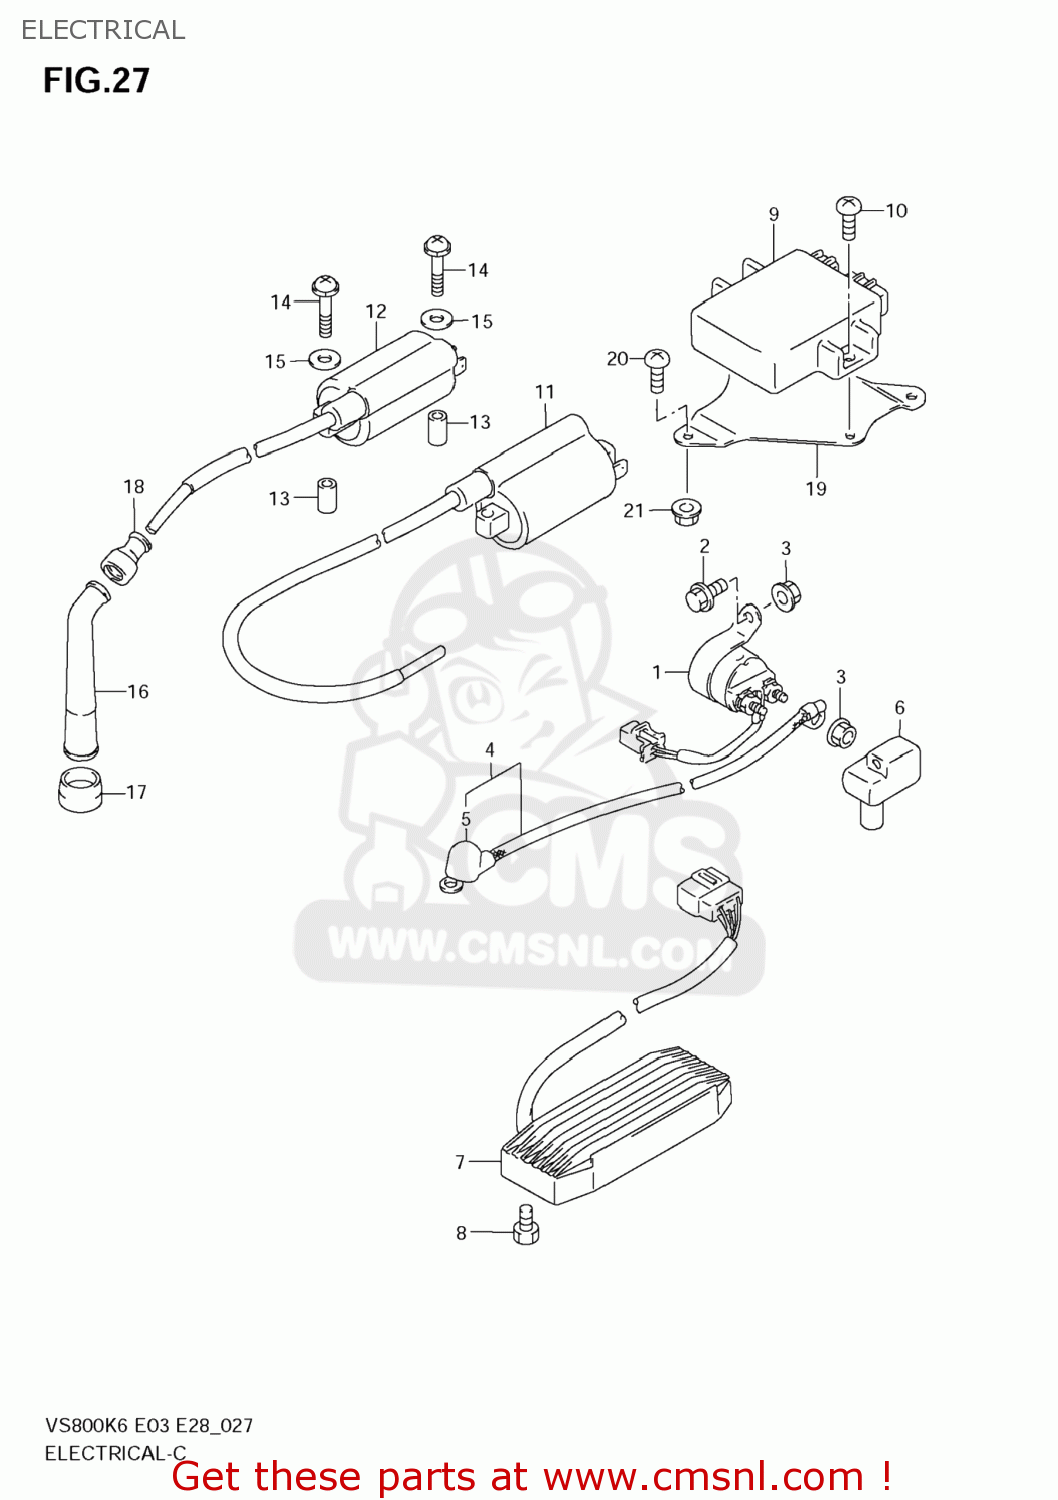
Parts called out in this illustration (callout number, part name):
1	RELAY ASSY,STARTING MOTOR
2	BOLT
3	NUT
4	WIRE,STARTER MOTOR LEAD
5	CAP,STARTER MOTOR LEAD
6	CAP,STARTER RELAY
7	RECTIFIER ASSY
8	BOLT
9	IGNITOR ASSY
10	SCREW
11	COIL ASSY,IGNITION RR
12	COIL ASSY,IGNITION FR
13	SPACER(6.4X10X19)
14	SCREW(5X38)
15	WASHER
16	CAP,SPARK PLUG
17	SEAL,SPARK PLUG
18	SEAL,HIGH TENSION CORD
19	PLATE,IGNITOR FITING
20	SCREW
21	NUT
